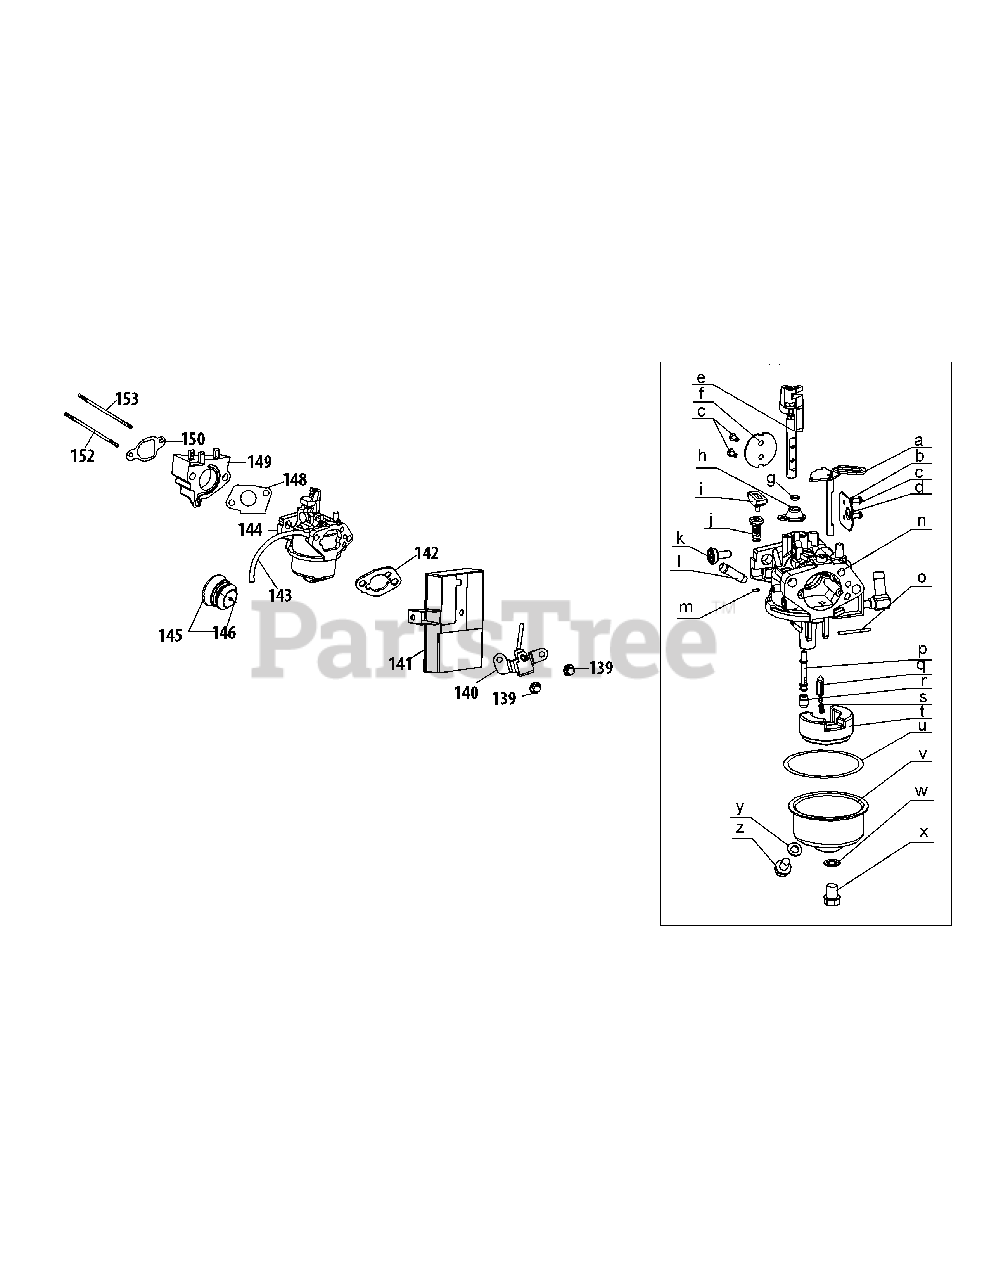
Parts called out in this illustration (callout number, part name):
139	NUT M6
140	CHOKE CONTROL
141	HEATER BOX
142	GASKET,AIR CLEANER
143	PRIMER HOSE
144	CARBURETOR ASSEMBLY
145	PRIMER ASSEMBLY
146	PRIMER
148	CARBURETOR GASKET
149	CARBURETOR INSULATOR
150	CARBURETOR INSULATOR GASKET
152	STUD M6-8×118
153	STUD M6-8×100
